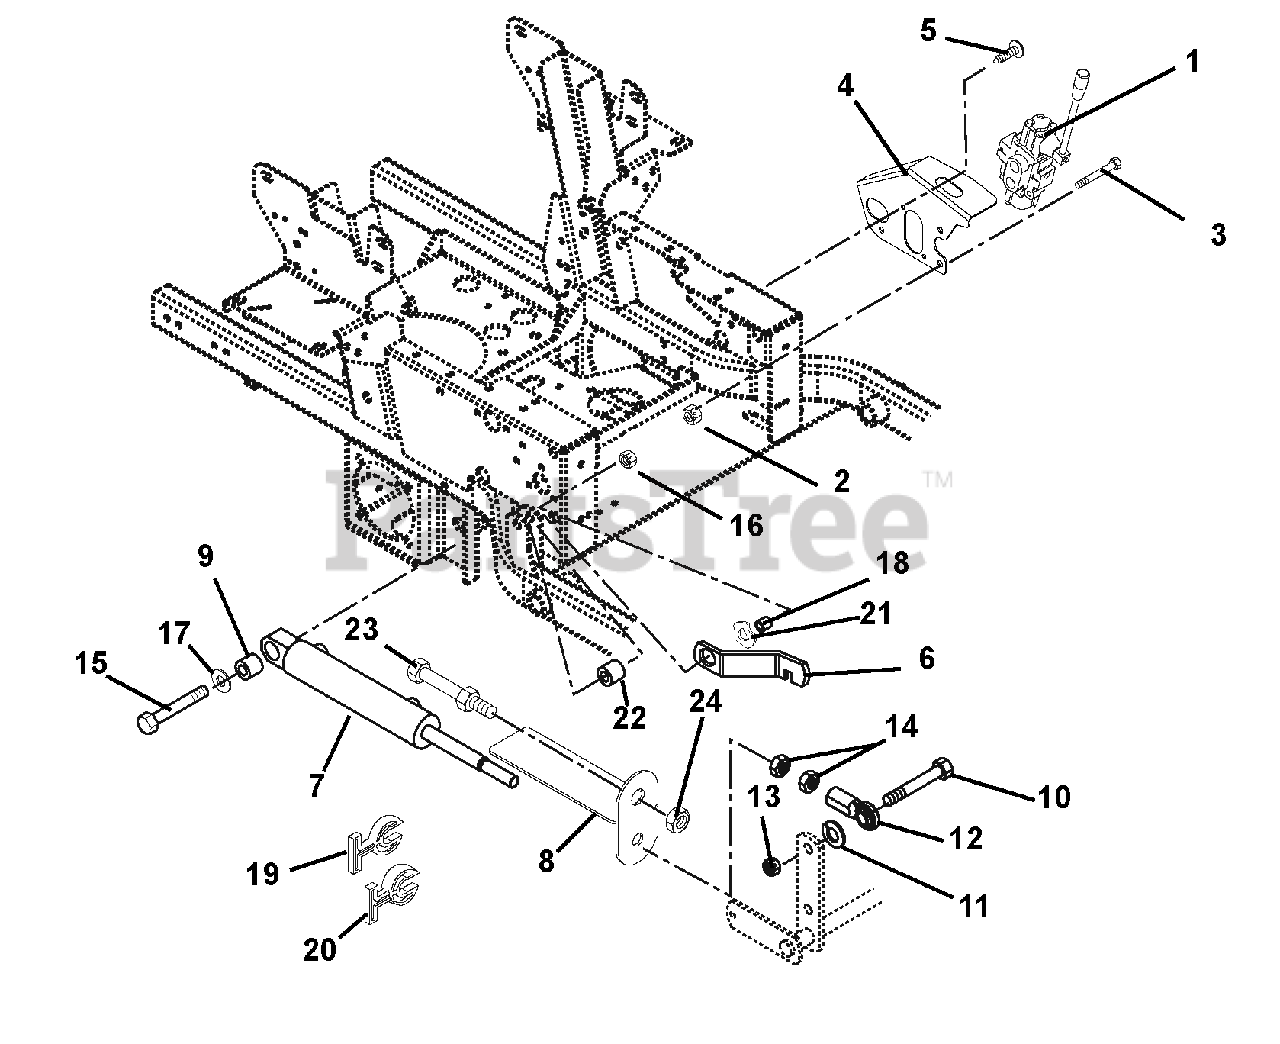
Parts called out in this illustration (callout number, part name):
1	VALVE, HYDRAULIC
2	@NUT-LK-TOP-FLG .31-18 YWZC
3	@BLT-HEX .31-18X2.50 GR5 YWZC
4	BRKT, VALVE MOUNTING
5	@SCR-TAP .38-16X.50 HWH TR YWZ
7	CYLINDER, LIFT
8	CUT INDICATOR/GUARD - BLACK
9	BUSHING, .516X1.000X1.050 LG
10	BLT-HEX .62-11X2.25 YWZC GR8
11	@WSHR-LK .62X.156 REG YWZC
12	ROD END, 5/8 RH - FEMALE
13	@NUT-LK-CTR .62-11 YWZC
14	NUT-JAM .625-18 YWZC
15	@BLT-HEX .50-13X3.50 GR5 YWZC
16	@NUT-LK-TOP-FLG .50-13 YWZC
17	WSHR-FL-STL .515X1.625X.250 YZ
18	BSHG-FLG .515X.750X.285X1.120
19	STOP, CYLINDER .34 THK
20	STOP, CYLINDER .680 THK
21	WASHER-WAVE .760X1.120X.080
22	SPACER .516X1.000X.875
24	NUT-JAM .75-16 YWZC
